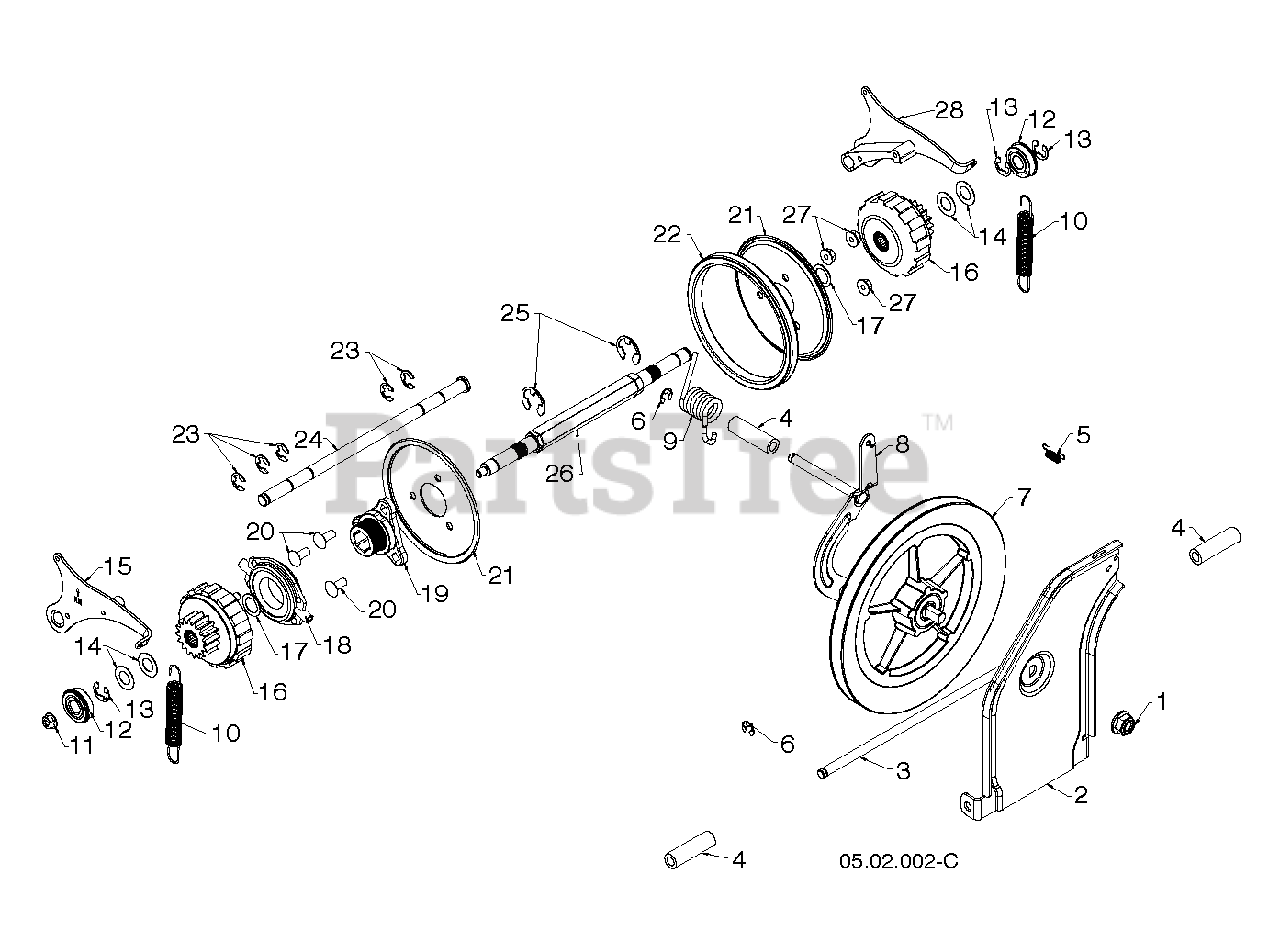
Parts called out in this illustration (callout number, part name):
1	NUT, 1/2-13 HEX FLG NYLOC ZD
2	Plate, Swing Friction Pulley 47
3	ROD.TIP.PLATE
4	SPACER YOKE, TORSION SPRING
5	SPRING LATCH
7	Friction Disc Combo Pulley
9	Drive Torsion Spring
10	PS Extension Spring
11	Flange Hex Lock Nut, 5/16-18
12	Bearing, 9/16" Id. Snr
13	Retaining Ring
14	Flat Washer, .637Id X 1.00Od X 21Ga
15	PAWL.ASM.RH.SNOW
16	Gear Assembly Planetary
17	Flat Washer, .59Id X 1.065Od X 25Ga
18	TRUNNION BEARING ASSY
19	HUB.RUBBER.WHEEL
20	BOLT.5/16-18.
21	Wheel Plate, Rubber Black
22	Ring, Rubber
23	E-Ring Clip, .500 Shaft
24	ROD ROD, PAWL ROD
26	Power Str Shaft
27	NUT.LOCK.5/16-18
28	PAWL.ASM.LH.SNOW
